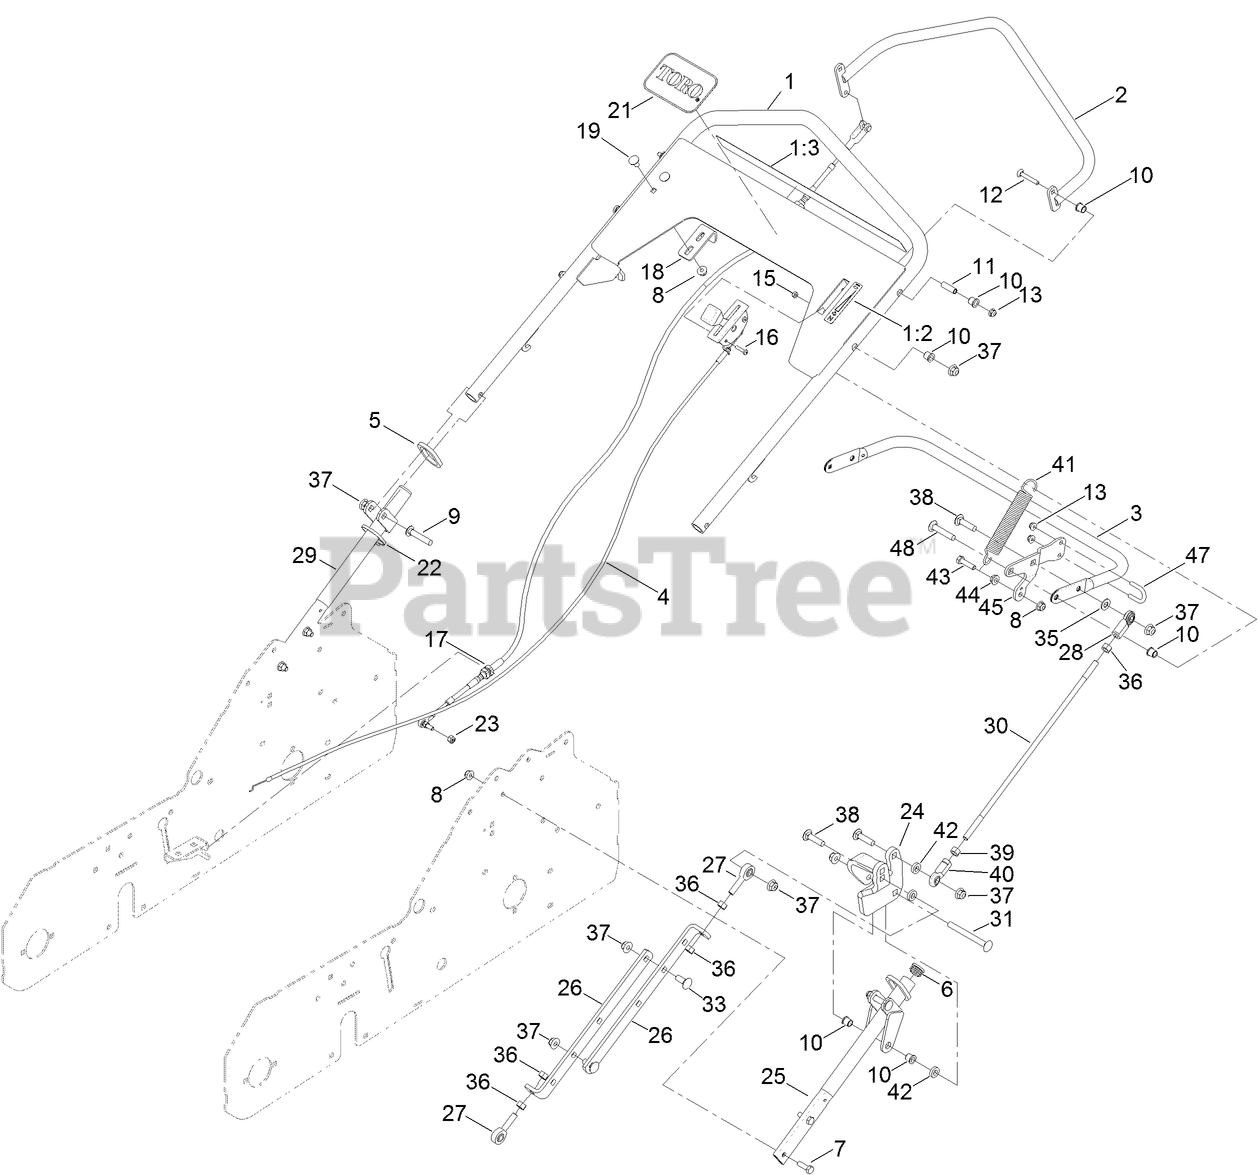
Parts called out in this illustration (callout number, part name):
1	HANDLE ASM
1:2	DECAL-THROTTLE, CHOKE
1:3	DECAL-AERATOR CONTROL PANEL
2	TUBE-CONTROL
3	TUBE-HANDLE LIFT
4	CONTROL-THROTTLE
5	RING-HANDLE LOCK
7	SCREW-HH
8	NUT-HF, NI
9	SCREW-CARR
10	BEARING
11	BUSHING-PIVOT
12	SCREW-CARR
13	NUT-HF
15	NUT-LOCK, NI
16	SCREW-PPH
18	ANGLE-STOP
19	SCREW-CARR
21	DECAL
22	TIE-CABLE
23	NUT-LOCK
24	BRACKET-TRUNNION
25	HANDLE-LOWER, LH
26	LINK-LIFT
27	BALLJOINT
28	JOINT-BALL, END
29	HANDLE-LOWER
30	ROD-UPPER LINK
31	SCREW-CARR
33	BOLT-CARR
35	WASHER-FLAT
36	NUT-HEX
37	NUT-HF, NI
38	SCREW-CARR
39	NUT-HEX, LH
40	JOINT-BALL END, LH
41	SPRING-EXTENSION
42	SPACER
43	SCREW-HH
44	NUT-HF
45	BRACKET-SPRING
48	BOLT-CARRIAGE
